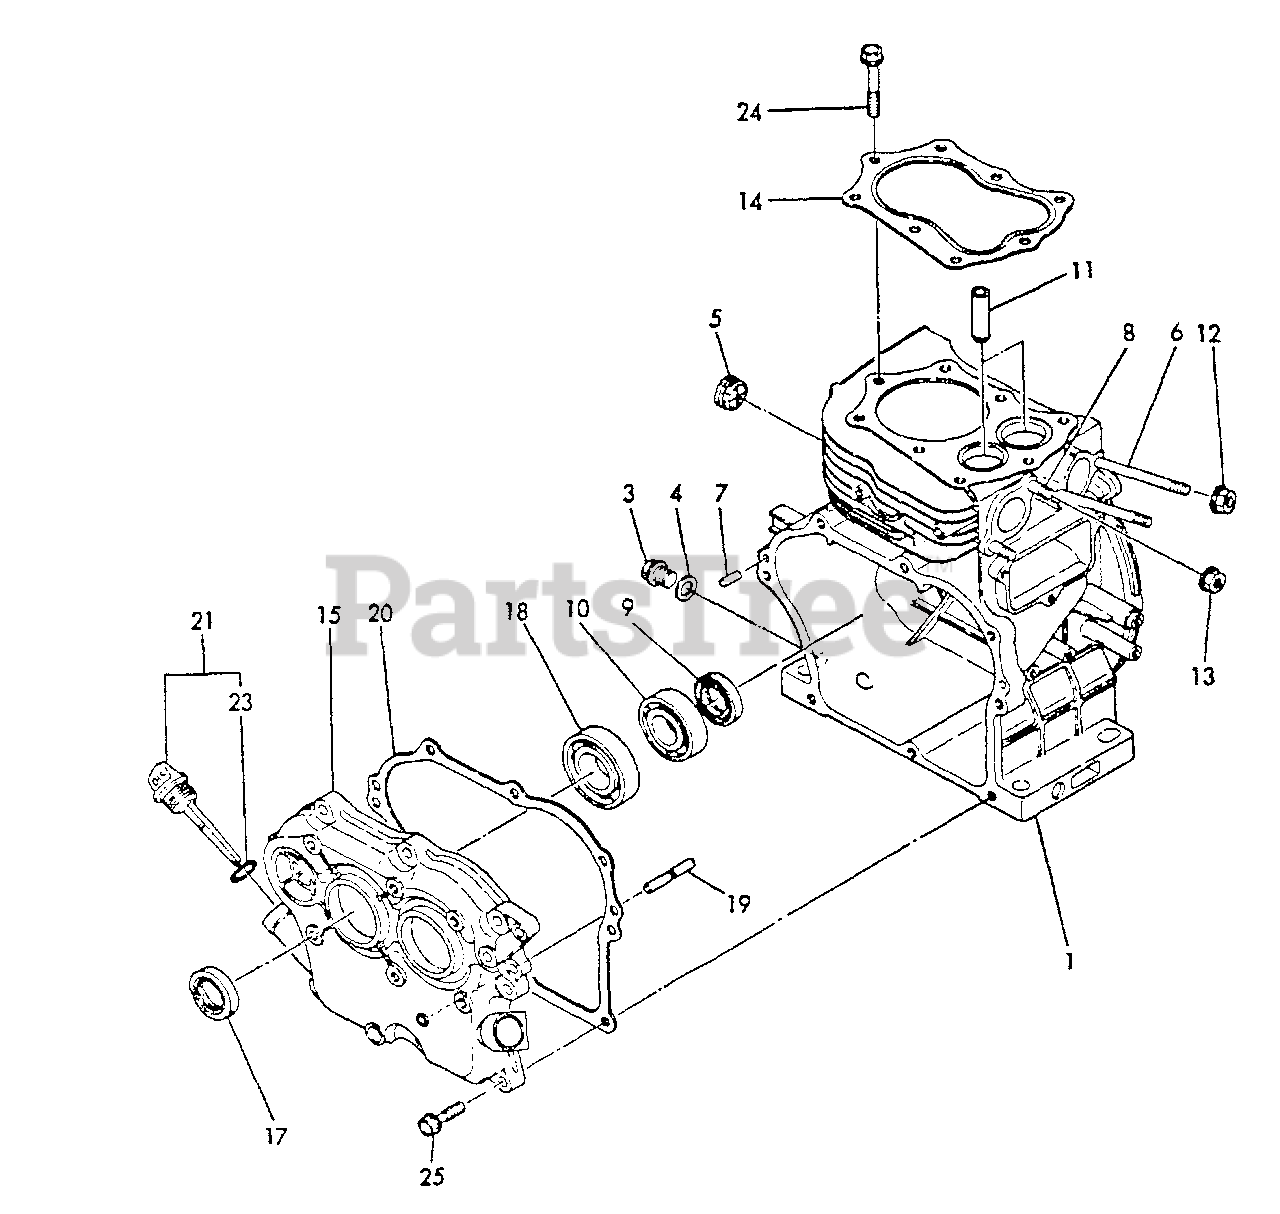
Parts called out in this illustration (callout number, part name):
1	CYLINDER BLOCK SET
3	PLUG, DRAIN
4	GASKET
5	PLUG
6	BOLT - 6X90
7	PIN - 6X16
8	STUD - 8X18 -- PLATED
9	SEAL, OIL
10	BEARING, BALL - 6205C3
11	GUIDE, VALVE
12	NUT - 6 -- FLANGE
13	NUT - 8
14	GASKET, CYLINDER
15	SIDE COVER ASSY
17	SEAL, OIL
18	BEARING, BALL - 6206C4
19	SHAFT, GOVERNOR
20	GASKET, SIDE COVER
21	OIL FILLER CAP ASSY
23	O-RING - 18
24	BOLT - 8X50
25	BOLT - 8X30 -- PLATED
